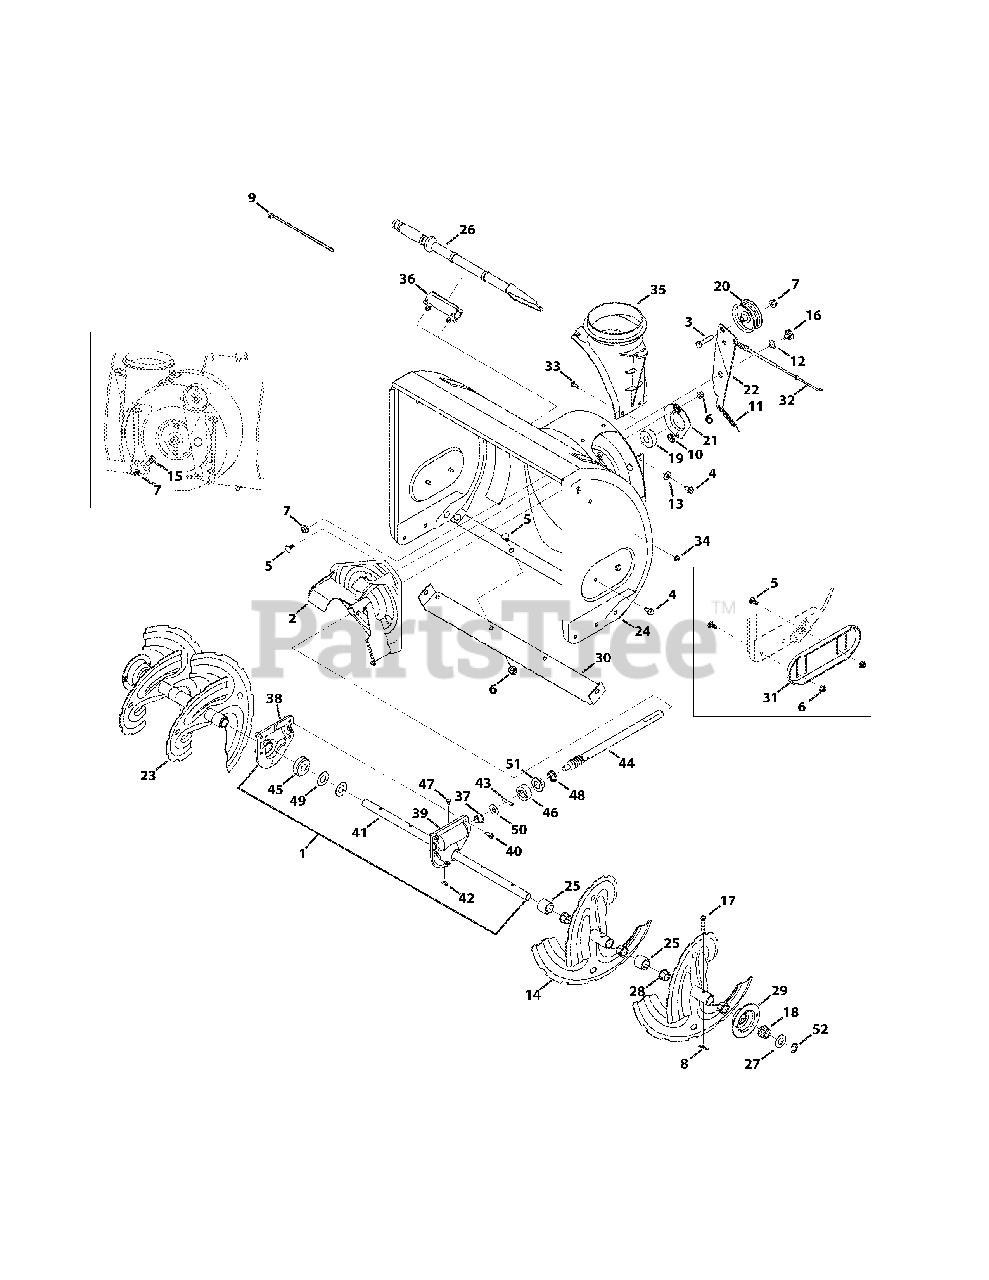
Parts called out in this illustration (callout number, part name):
1	Auger Gearbox 26", includes 37-51
2	Impeller Assembly, 12" Dia.
3	Hex Head Screw, 3/8-16 x 1.75
4	Screw, 5/16-18 x .750
5	Bolt, Carriage, 5/16-18 x .750
6	Nut, Flange lock, 5/16-18
7	Nut, Flange lock, 3/8-16
8	Bow-Tie Cotter Pin
9	Cable Tie, 7"
10	Nut, Push-on, .25 Dia.
11	Extension Spring, .38 x 4.59
12	Washer, Wave, .625 x .885
13	Washer, Bell, .340 x .872
14	Spiral Assembly, LH
15	Bolt, Shoulder, .496 x .336 x 3/8-16
16	Screw, Shoulder, .625 x .17 x 3/8-16
17	Shear Pin, .25 x 1.50
18	Hex Flange Bearing
19	Bearing, Ball, .75 x 1.85
20	Pulley, Idler, Flat, 2.75
21	Bearing, 1.85 ID
22	Auger Idler Bracket
23	Spiral Assembly, RH
24	Auger Housing Assembly
25	Spacer, 1.25 x .75 x 1.00
26	Clean-Out Tool
27	Washer, Flat, .76 x 1.49
28	Bushing, Flange, .800 x .910
29	Hex Bearing Housing
30	Shave Plate, 2.25 x 25.66
31	Deluxe Slide Shoe
32	Auger Drive Clutch Cable
33	Screw, Carriage, 1/4-20 x .75
34	Nut, Flange lock, 1/4-20
35	Chute Adapter
36	Clean-Out Tool Mount
37	Bearing, Flange, .50 x .75 x .59
38	Reducer, RH
39	Reducer, LH
40	Screw, 1/4-20 x 0.750
41	Auger Axle, 26"
42	Key, Hi-Pro, 3/16 x 5/8
43	Dowel Pin, .25 x 1.25
44	Worm Shaft, .75
45	Gear Worm, 20T
46	Collar Thrust, .756 x .600
47	Plug, 1/4 x .437
48	Oil Seal, .75 x 1.131 x .188
49	Washer, Flat, .760 x 1.50
50	Washer, Flat, .51 x 1.12
51	Bearing, Flange, .75 x 1.00 x .59
52	E-Ring, .750
